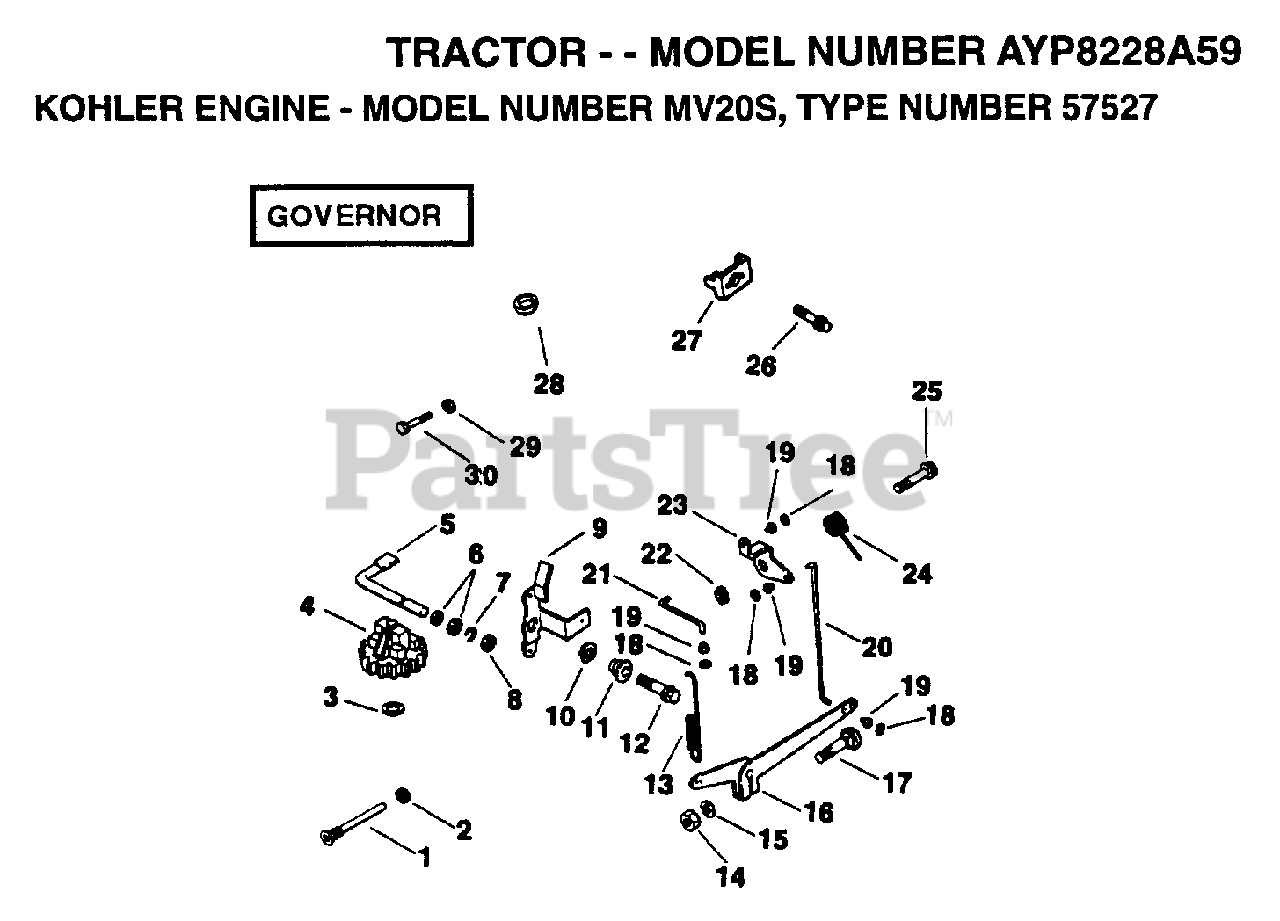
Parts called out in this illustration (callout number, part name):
1	PIN
2	WASHER
3	WASHER
6	WASHER
7	RETAINER
8	WASHER, PLAIN 1/4
10	WASHER
12	SCREW, 1/4-20 X 1
14	NUT
15	WASHER
22	WASHER, PLAIN 1/4
25	SCREW, HEX 1/4-20 X 5/8
26	CLAMP
27	SCREW
29	NUT, HEX #10-32
